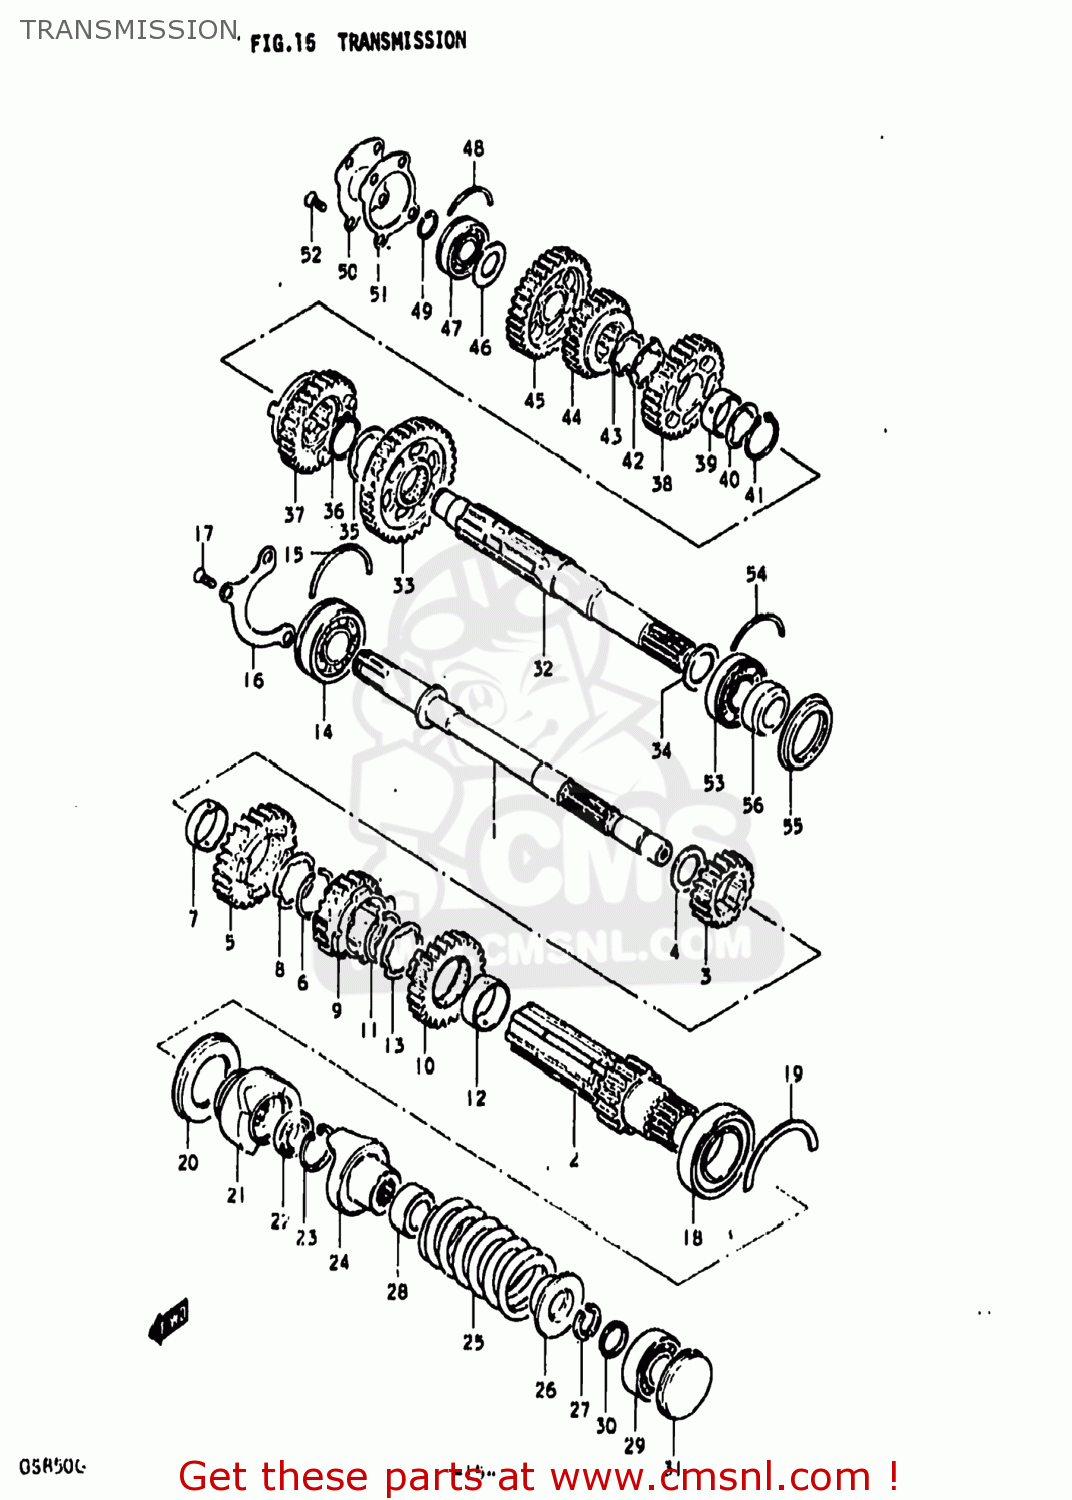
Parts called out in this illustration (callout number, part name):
1	SHAFT,COUNTER
2	SHAFT,OUTER COUNTER
3	GEAR,SECOND DRIVE
4	WASHER (21X35X2)
5	GEAR,FIFTH DRIVE
6	RING,SNAP
7	SPACER,DRIVE GEAR
8	LOCK WASHER,5TH DR GEAR SPACER
9	GEAR,THIRD DRIVE
10	GEAR,FOURTH DRIVE
11	RING,SNAP
12	SPACER,DRIVE GEAR
13	LOCK WASHER,5TH DR GEAR SPACER
14	BEARING(25X62X17)
15	C-RING
16	RETAINER,CNTR SHAFT BEARING
17	SCREW
18	BALL BEARING 32X58X13
19	C-RING
20	SEAL,OIL(40X58X7)
21	DOG,OUTPUT CAM
22	SEAL,OIL(20.6X31X6)
23	CIRCLIP
24	DOG,INPUT CAM
25	SPRING
26	STOPPER,CAM DOG
27	STOPPER,CAM DOG
28	GUIDE,CAM DOG SPRING
29	BEARING
30	SPACER (17X21X3.5)
31	PLUG
32	SHAFT,DRIVE
33	GEAR,FIRST DRIVEN
34	WASHER, LH
35	WASHER,LOCK
36	CIRCLIP
37	GEAR,FOURTH DRIVEN
38	GEAR,THIRD DRIVEN
39	BUSH,3RD DRIVEN GEAR
40	WASHER,LOCK
41	CIRCLIP
42	WASHER
43	WASHER,LOCK
44	GEAR,FIFTH DRIVEN
45	GEAR,SECOND DRIVEN
46	WASHER
47	BEARING(20X47X14)
48	C RING
49	CIRCLIP
50	PLATE,DRIVESHAFT
51	GASKET,DRIVESHAFT PLATE (MCA)
52	SCREW
53	BEARING
54	C RING
55	SEAL,OIL(35X52X6)
56	SPACER,DRIVESHAFT,LEFT
